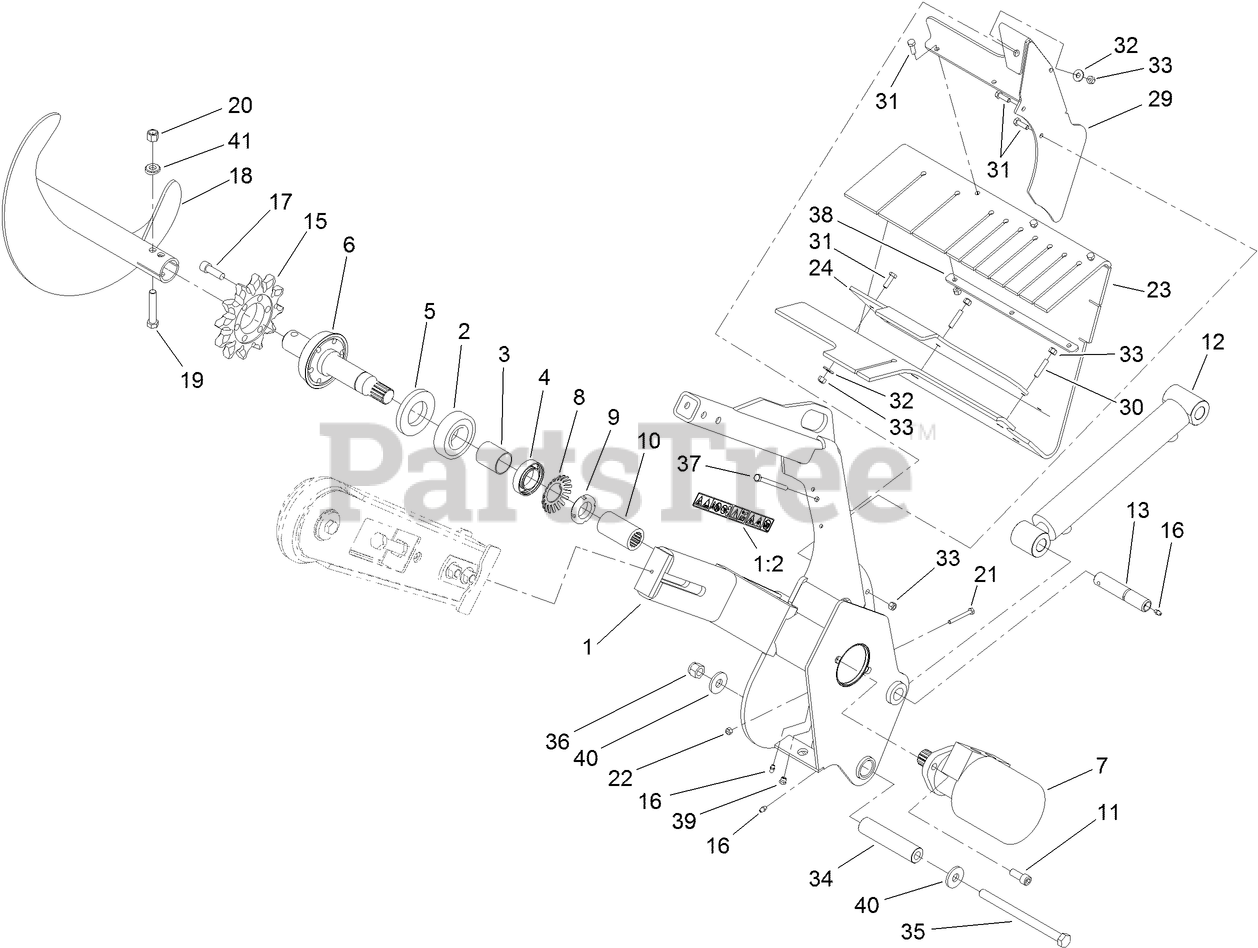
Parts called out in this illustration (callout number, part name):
1	TRENCHER HEAD ASM
1:2	DECAL-DANGER
2	BEARING-BALL
3	SPACER
4	BEARING-BALL
5	SEAL-GREASE
6	SHAFT-TRENCHER
7	MOTOR-HYD
8	LOCKWASHER-BEARING
9	LOCKNUT-BEARING
10	SPLINE-COLLAR
11	SCREW-HSH
12	HYD CYLINDER ASM
13	PIN-PIVOT
15	SPROCKET-TRENCHER
16	FITTING-GREASE
17	SCREW-HSH
18	AUGER-TRENCHER
19	SCREW-HH
20	NUT-LOCK, NI
21	SCREW-HH
22	NUT-LOCK, NI
23	SHIELD-DIRT
24	BAR-CLAMP
29	BRACKET-SHIELD
30	SCREW-HSH
31	SCREW-HH
32	WASHER-FLAT
33	NUT-LOCK, NI
34	SPACER-PIVOT
35	BOLT-HH
36	NUT-LOCK, NI
37	SCREW-HH
38	PLATE-STRAP, SHIELD
39	FITTING-LUBE
40	WASHER-HARDENED
41	WASHER-SADDLE
